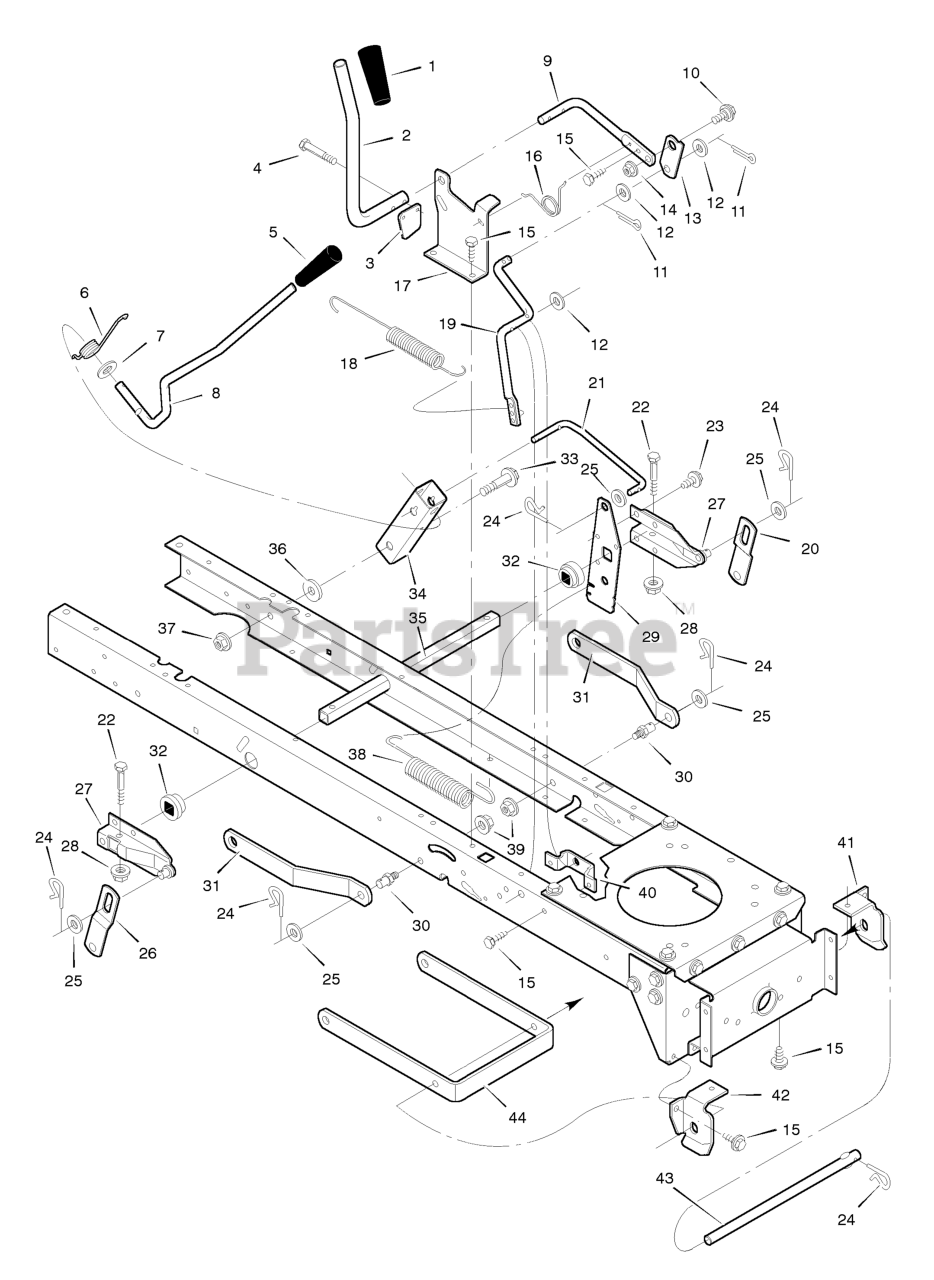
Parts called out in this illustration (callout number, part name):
1	Grip
2	Handle, PTO
3	Pad, Switch
4	Screw, Hex
5	Grip
8	Lever, Lift
9	Lever, PTO
10	Bolt, Shoulder
11	Pin, Cotter
12	Washer
13	Link, PTO
14	Nut, Flange
17	Bracket, PTO
19	Crank, PTO
20	Link, Left Lift
21	Link, Lift
24	Pin, Hair
26	Link, Right Lift
27	Lever Assembly, Lift
28	Nut, Flange
29	Plate, Lift Arm
30	Pin
31	Bracket, Rear Suspension
32	Bushing
33	Bolt, Shoulder
34	Bracket, Pivot
35	Tube, Deck Lift
37	Nut, Flange
39	Nut, Flange
40	Bracket, PTO
41	Hanger, Left Deck
42	Hanger, Right Deck
43	Rod, Hanger
44	Bracket, Suspension
